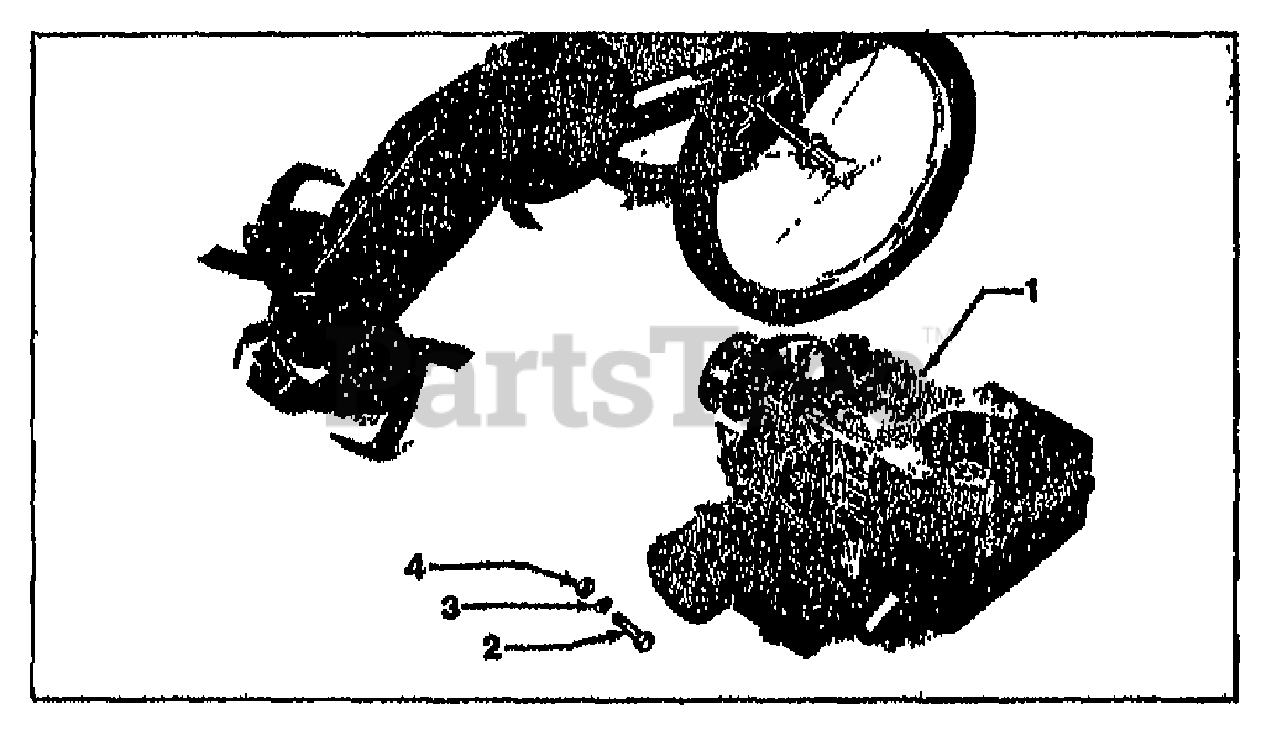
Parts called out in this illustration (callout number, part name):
1	ENGINE, TECUMSEH H30 3HP
2	SCR-HH 5/16-18X1.25 G5ZP (MOUNTS ENGINE TO CHASSIS)
3	WASHER-LK .312 ZP
4	NUT-HEX 5/16-18 ZP
